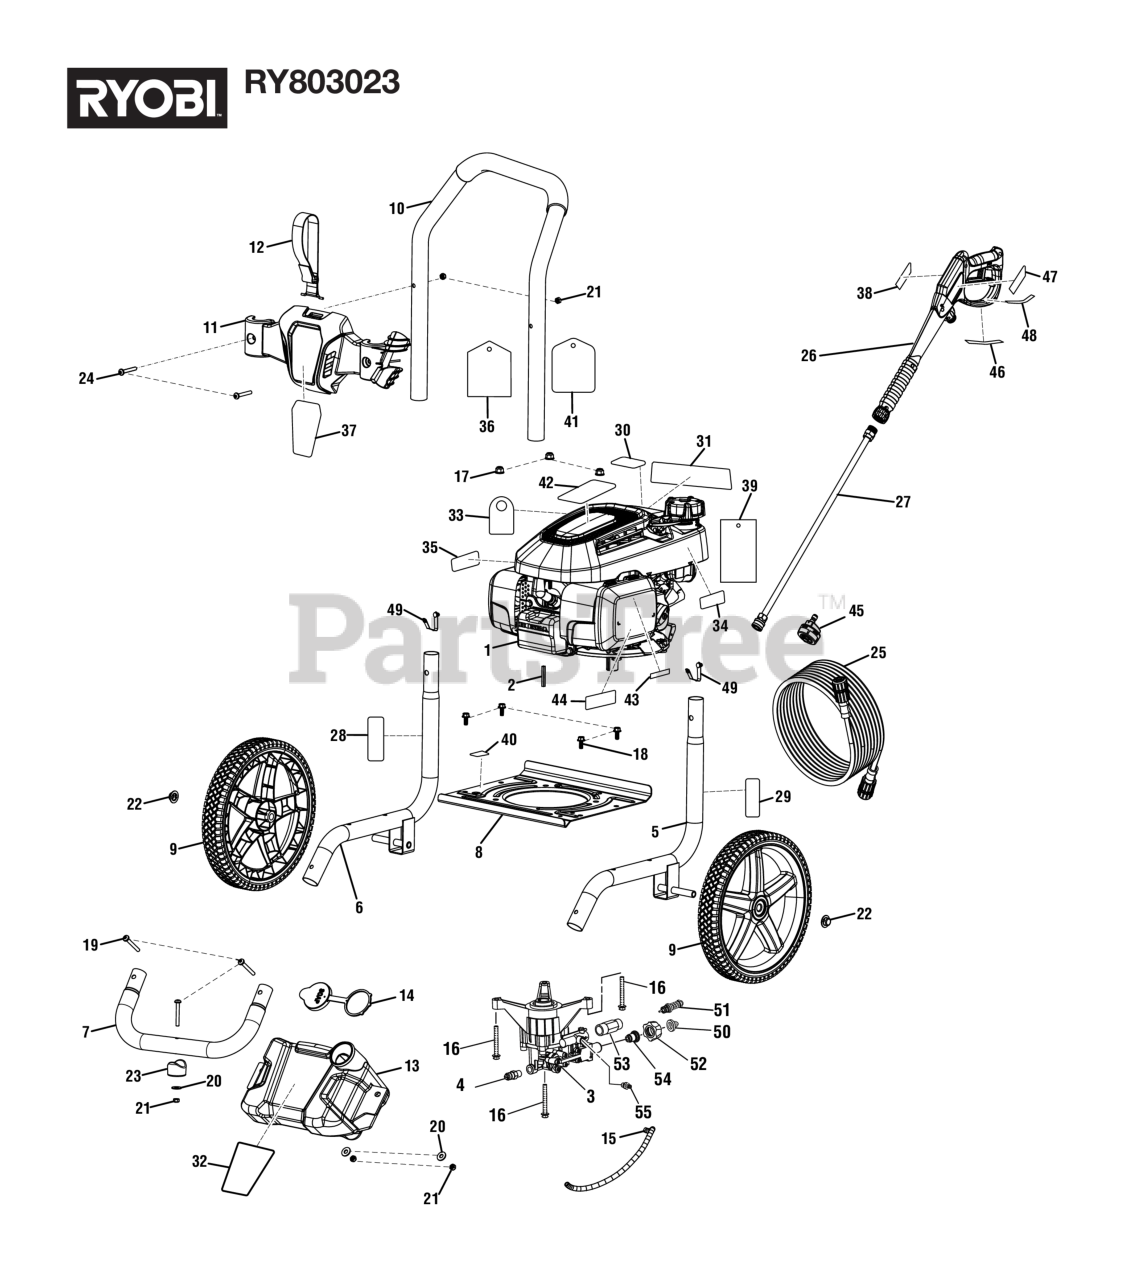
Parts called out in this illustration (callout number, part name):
1	Engine
2	Output Shaft Key (3/16 in. x 40 mm)
3	Pump (Inc. Key Nos. 50-55)
4	Thermal Release Valve.
5	Main Frame Assembly (Left, Inc. Key No. 42)
6	Main Frame Assembly (Right, Inc. Key No. 42)
7	Frame Assembly (Front)
8	Engine Plate
9	Wheel
10	Handle Assembly w/ Foam Grip
11	PERFORMANCE PANEL, W/ WAND HOLDER
12	Hose Holder Strap
13	Detergent Tank
14	Detergent Tank Cap
15	Detergent Injection Hose
16	Flange Bolt (M8 x 1.25 x 60 mm, Hex Hd.)
17	Lock Nut (M8 x 1.25 mm, Flange)
18	Flange Bolt (M6 x 1 x 16 mm, Hex Hd.)
19	Screw (M6 x 1 x 48 mm, T30 Torx Pan Hd.)
20	Washer (1/4 in.)
21	Lock Nut (M6 x 1)
22	Push Cap Nut (1/2 in.)
23	Rubber Foot
24	Bolt (M6 x 42 mm, T30 Torx Hex Hd.)..
25	Hose (35 ft.)
26	Trigger Handle Assembly
27	Extension Wand
28	Data Label
29	Warning Label
30	UL Fire Warning Label Spark Arrestor)
31	Danger Label
32	Detergent Tank Label
33	Oil Dipstick Hangtag
34	No E85 Label
35	Hot Surface Label
36	Nozzle Hangtag
37	Performance Label
38	LABEL, TRIGGER HANDLE LOGO
39	Danger Hangtag
40	Oil Fill Location Label
41	Quick Start Hangtag
42	Recoil Label
43	EMC ICES-2/NMB-2 Label (Canada)
44	Inquires Label (Ryobi)
45	5-in-1 Nozzle
46	Trigger Handle Warning Label (English)
47	Trigger Handle Data Label
48	Label (Trigger Handle Warning, French & Spanish)
49	Lock Button w/Spring Clip.
50	Filter Screen (Pump Inlet)
51	Unloader Valve Assembly
52	Inlet Filter Adapter/Brass Insert
53	Outlet Tube
54	Inlet Filter Connector
55	Detergent Injector Assembly
